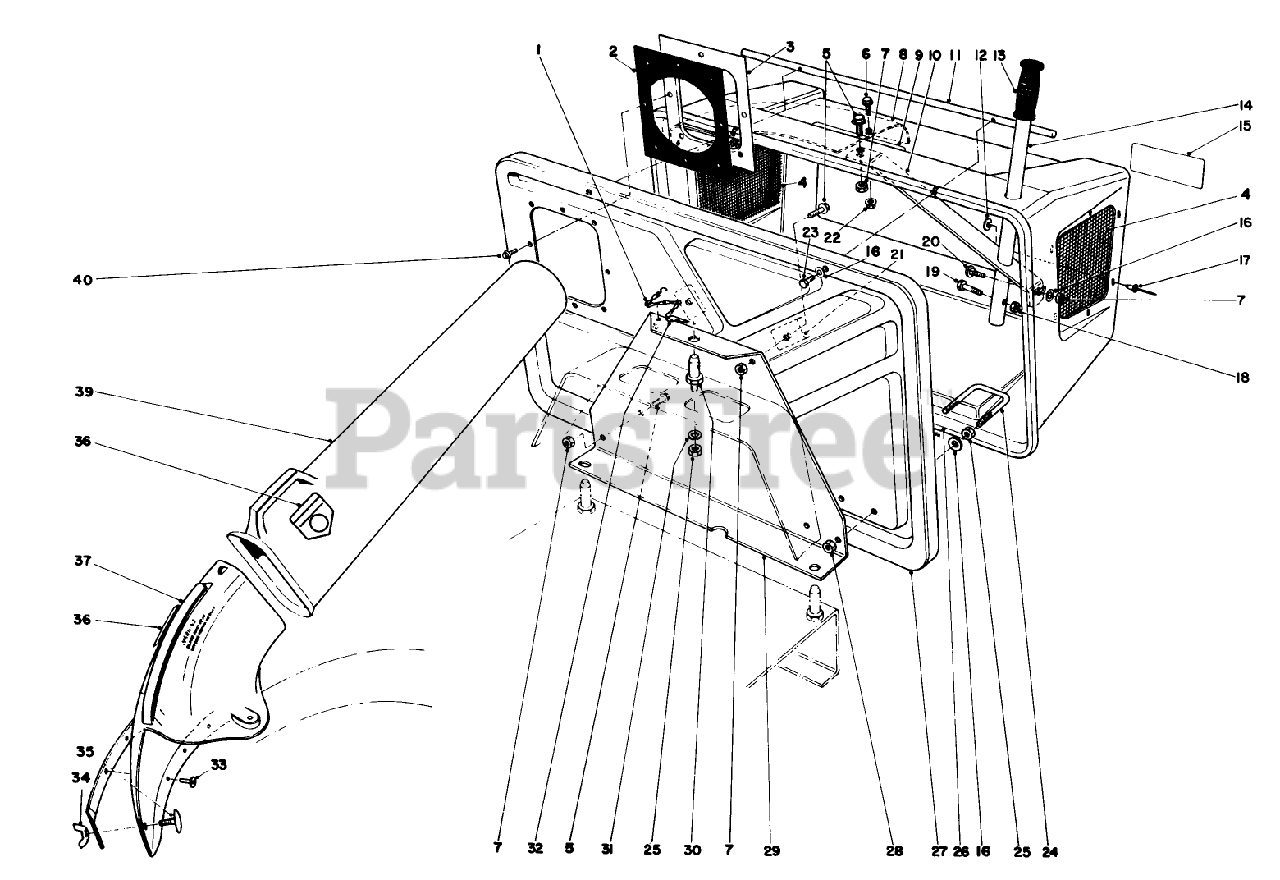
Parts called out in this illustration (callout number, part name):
4	SCREEN
5	SCREW-HHF
6	SCREW-HWH
7	NUT-HEX, SIDE DEFORM
8	DEFLECTOR
10	HANDLE GUIDE
11	PIVOT ROD
12	WASHER-FLAT
14	HANDLE TUBE
16	WASHER-FLAT
17	RIVET-POP
18	NUT-HEX, SIDE DEFORM
19	SCREW-HH
20	SCREW-CARR
22	NUT-LOCK, FLANGE
23	SCREW-HH
24	LATCH
25	NUT-HEX
26	HOPPER
28	NUT-LOCK, NI
31	WASHER-LOCK
33	RIVET 3/16 X 7/16
34	NUT-WING
39	DUCT ASM
40	SCREW
